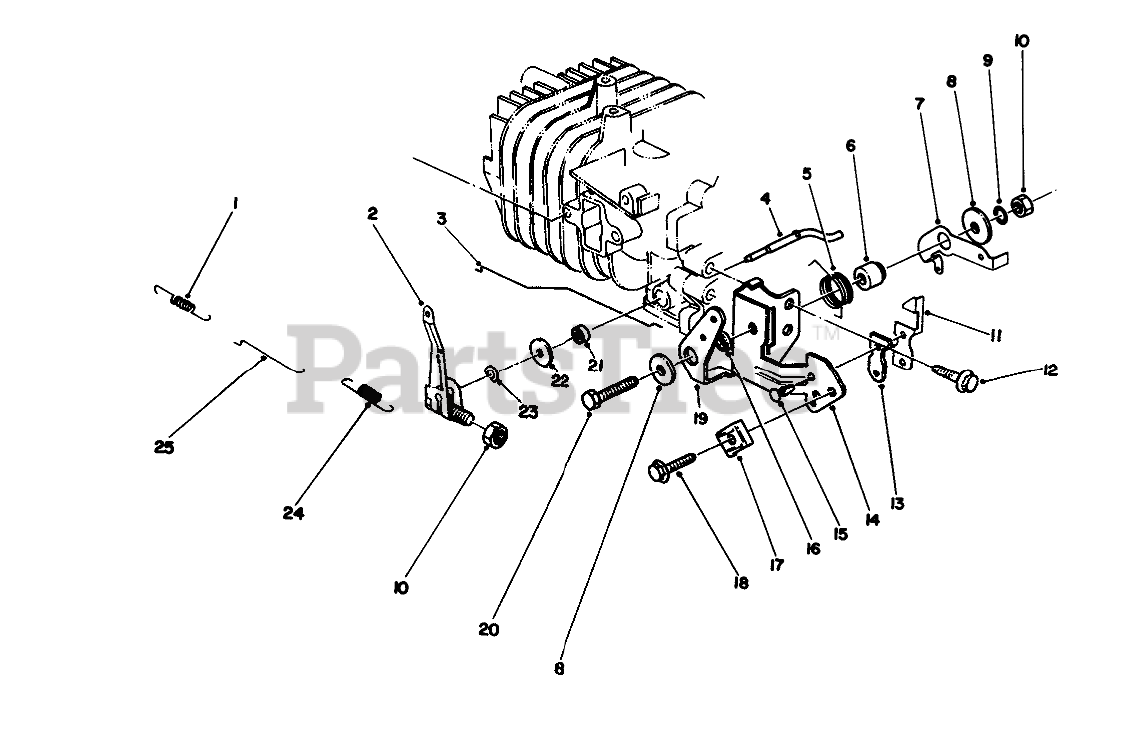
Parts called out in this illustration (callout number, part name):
1	SPRING
2	ARM-GOVERNOR
3	ROD-CHOKE
4	Shaft-Govemor
5	SPRING-CHOKE LEVER
6	Gov Lever Spacer
7	LEVER-SPRING, GOVERNOR
8	WASHER
9	LOCKWASHER
11	TERMINAL-KILL SWITCH
13	INSULATOR-KILL SWITCH
14	BRACKET-THROTTLE, CONTROL
15	KILL SWITCH RIVET
16	SPACER-CHOKE LEVER
17	CLAMP
19	LEVER-CONTROL, CHOKE
21	SEAL-OIL
22	WASHER
23	E-RING
24	SPRING-GOVERNOR
25	ROD-CARBURETOR
